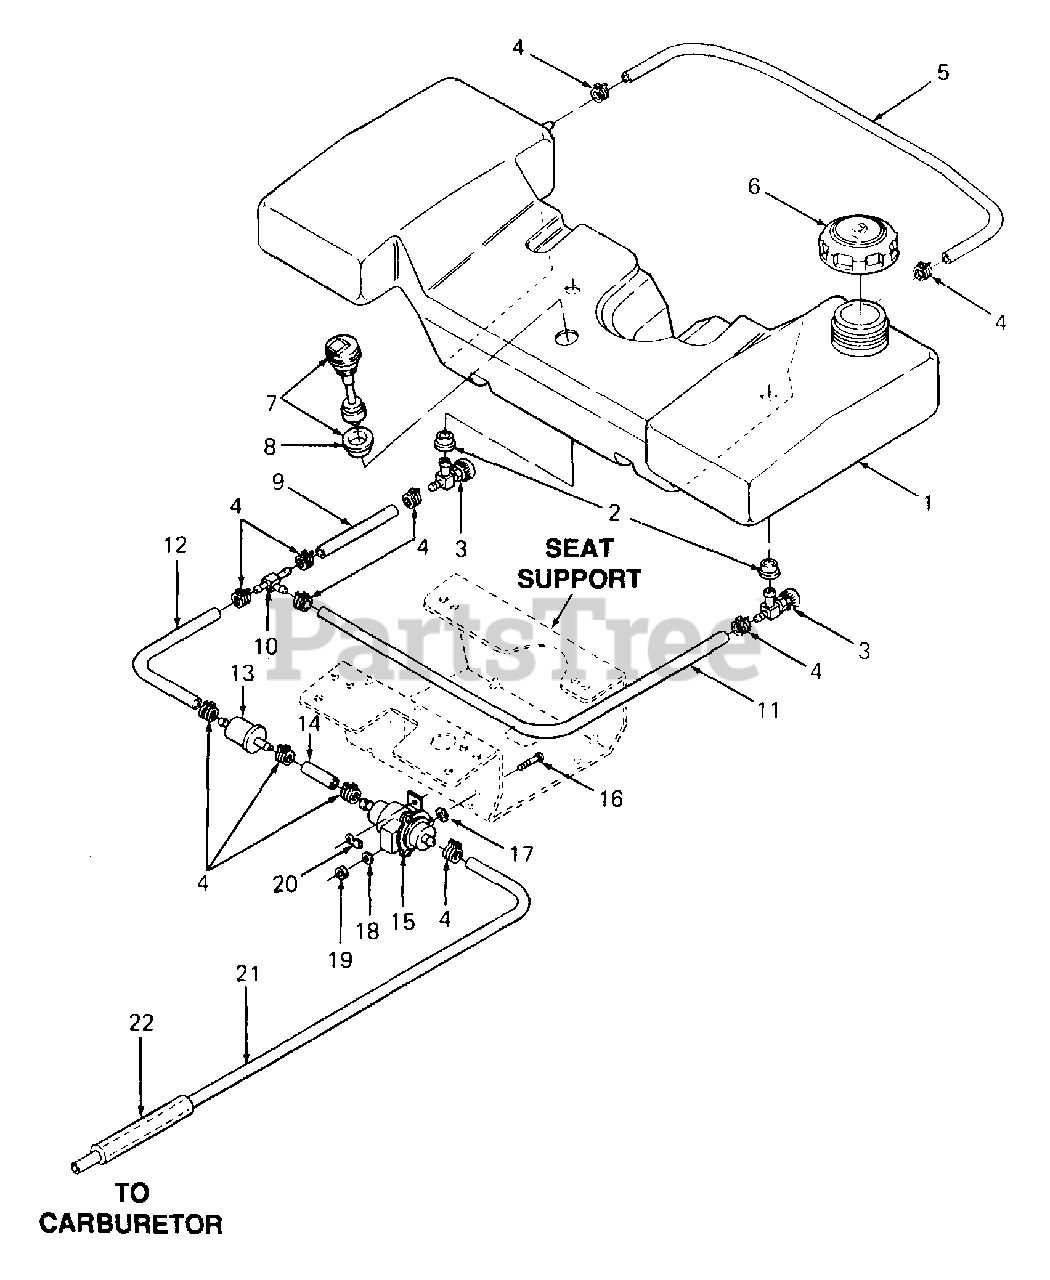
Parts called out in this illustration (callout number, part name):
1	Tank, Fuel
2	Bushing
3	Valve, Fuel Shutoff
4	Clamp, Hose
5	Line, Fuel - 24" Lg
6	Cap, Fuel
7	Sensor, Low Fuel
8	Bushing, Rubber
9	Line, Fuel - 5" Lg
10	T-Fitting
11	Line, Fuel - 17" Lg
12	Line, Fuel - 6" Lg
13	Filter, Fuel
14	Line, Fuel - 2" Lg
15	Fuel Pump Assy
16	Screw, Truss Mach, 1/4-20 X .62 Lg
17	Washer, Int-Ext Lock, 1/4
18	Washer, Spring, .265 X .562
19	Nut, Hex Flange Lock, 1/4-20
20	Lug, Quick Connect
21	Line, Fuel - 64" Lg
22	Insulator, Fuel Line - 24" Lg
